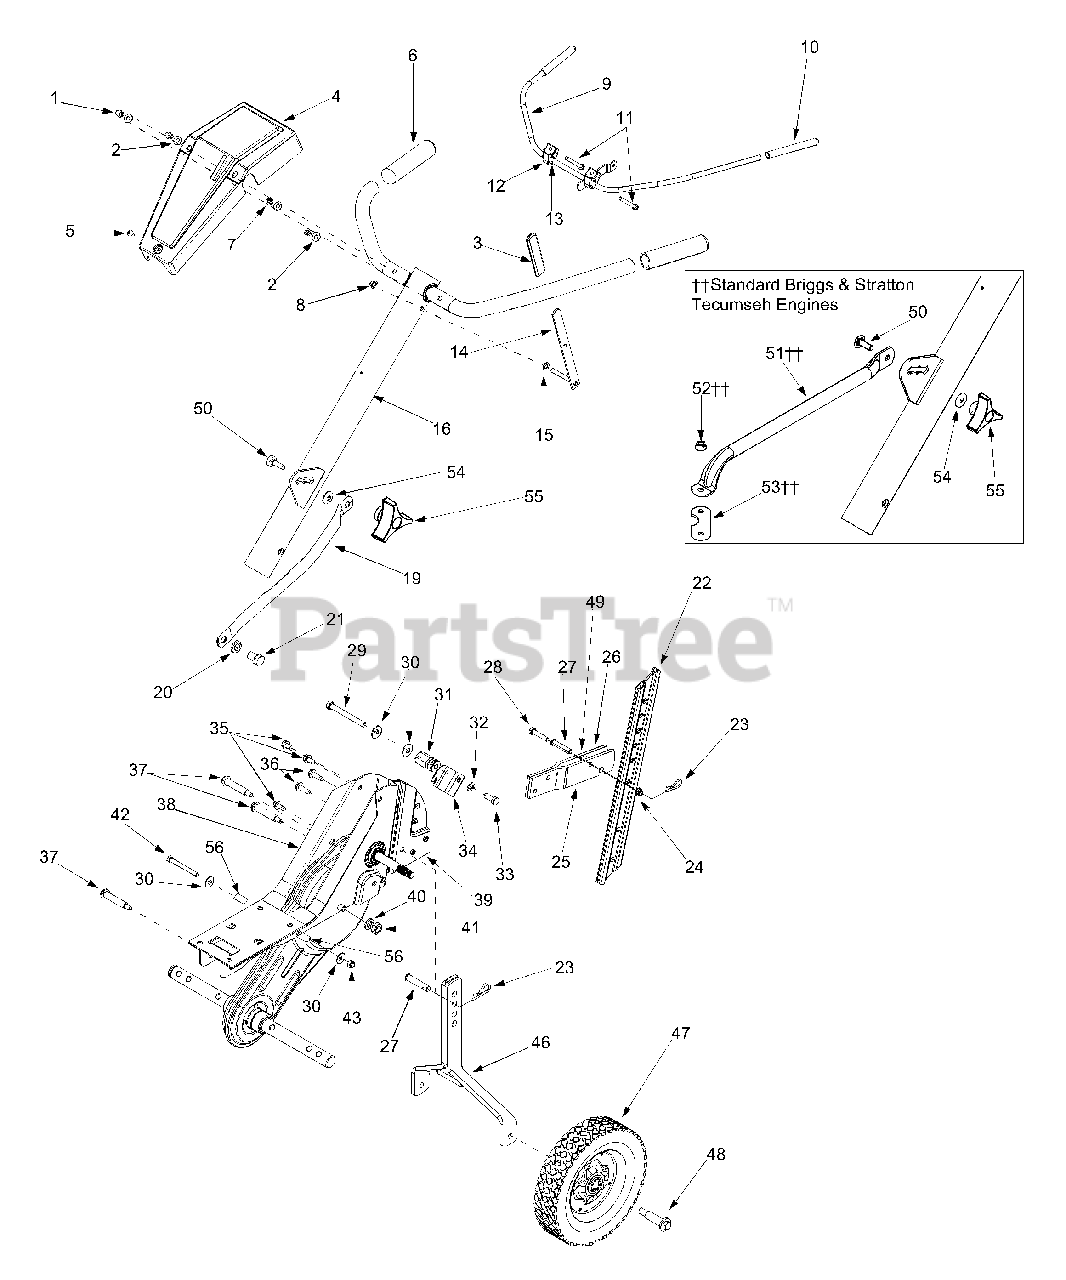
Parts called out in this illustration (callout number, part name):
1	Acorn Lock Nut 1/4-20
2	Flat Washer .271" I.D. x.630" O.D.
3	Reverse Handle Grip
4	Handle Cover w/o throttle
5	Truss Mach. Scr. #10 x 1/2" Lg.
6	Handle Grip
7	Hex Nut 1/4-20 Gr.2
8	Cap Speed Nut
10	Clutch Grip
11	Hex Bolt 1/4-20 x 2.25" Lg. Gr.5
12	Clutch Handle Holder
13	Flat Washer .385" I.D. x .62" O.D.
15	Flat Washer .344" I.D. x .62" O.D.
20	Lock Washer 1/2
21	Hex Bolt 1/2-20 Gr. 5
23	Cotter Pin
24	Hex Flange L-Nut 5/16-18 Thd. Gr.5
27	Clevis Pin
28	Hex Bolt 5/16-18 x 1.5" Lg.
29	Hex Bolt 5/16-18 x 3" Lg.
30	Wash. Bell .340" I.D. x .872" O.D.
31	Spec. Hex Nut
32	L-Wash. 5/16" I.D.
33	Hex Bolt 5/16-18 Gr. 5
35	Hex Washer Screw 5/16-18 x .62" Lg.
36	Hex Wash. Hd. TT-Tap Scr.
37	Shdl. Bolt 5/16-18
40	Lock Washer 7/16
41	Jam Nut 7/16-20 Gr. 2
42	Hex Bolt 5/16-18 x 2.75" Lg.
43	Hex Nylon Nut 5/16-18 Thd.
47	Wheel Ass'y 8" x 1.75"(Plastic)
48	Shoulder Screw.496 I.D. x 1.445 O.D.
49	Spacer
50	Carr. Bolt 5/16-18 x 1
53	Engine Brkt. (Std. B&S)
54	Bell. Wash.34" I.D.
55	Hand Knob
56	Spacer
